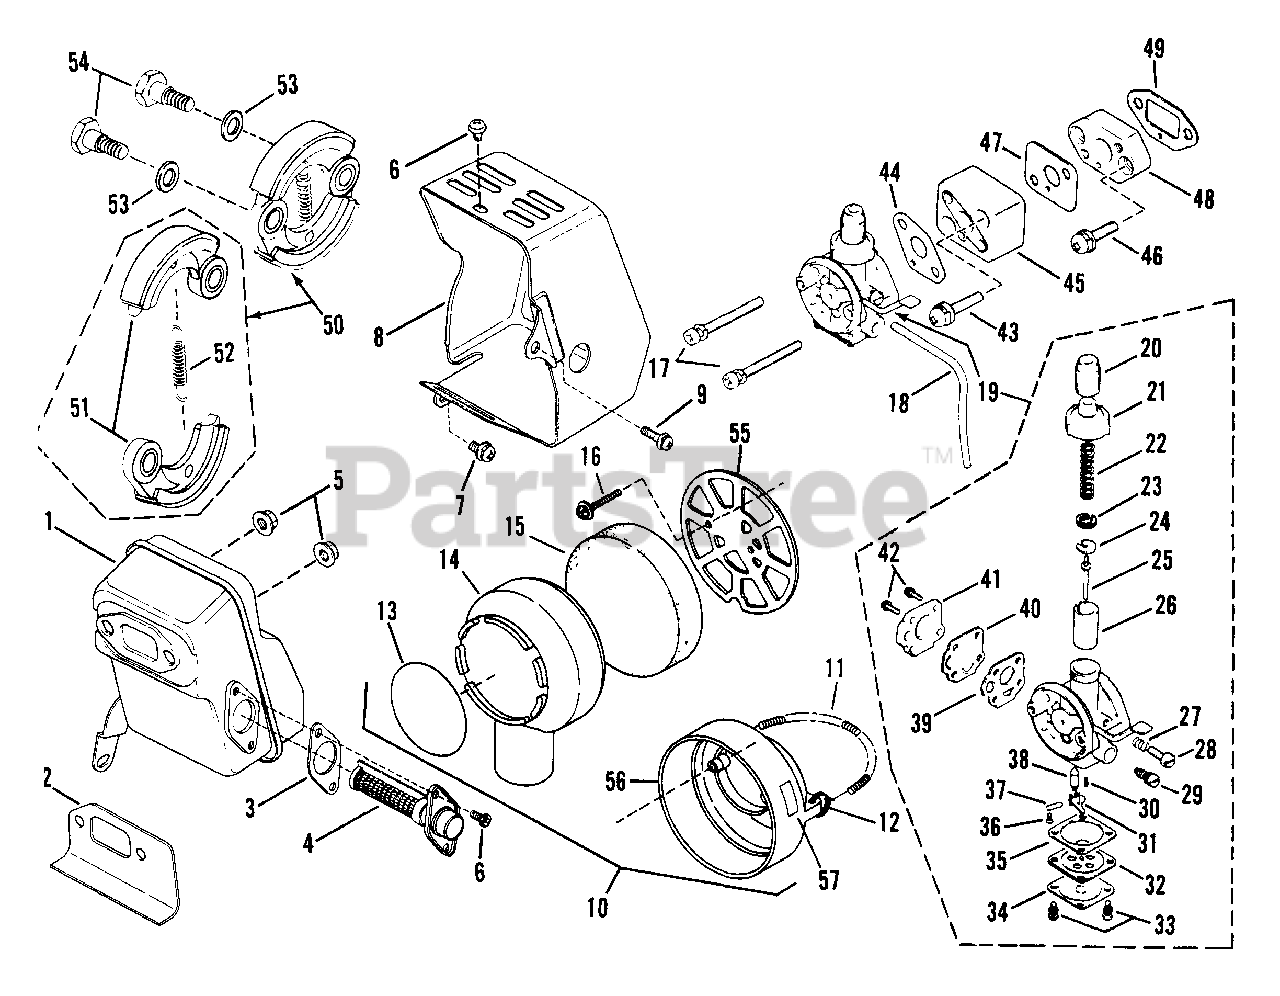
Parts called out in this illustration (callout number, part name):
1	MUFFLER
2	GASKET, Muffler
3	GASKET, Spark Arrester
4	SPARK ARRESTER
5	LOCKNUT
8	COVER, Muffler
9	SCREW
10	ASSM'Y, Air Cleaner
14	COVER, Cleaner
15	ELEMENT
16	SCREW, Cover
17	SCREW, Carburetor
18	TUBE, Overflow
19	CARBURETOR ASSM'Y.
20	CAP, Rubber
21	CAP, Mixing Chamber
22	SPRING, Throttle
23	CLIP, Needle
24	RETAINER, Spring
25	NEEDLE, Jet Assm'y.
26	VALVE, Throttle
27	SPRING, Throttle Adj. Screw
28	SCREW, Throttle Adj.
29	NEEDLE, Main Jet Assm'y.
30	SPRING, Inlet Valve
31	ARM, Float
32	DIAPHRAGM, Main Assm'y.
34	COVER, Main Daiphragm
35	GASKET, Main Diaphragm
36	SCREW, Float Pin Set
37	PIN, Float
38	VALVE, Float
39	GASKET, Main Diaphragm
40	DIAPHRAGM, Pump
44	GASKET, Carburetor
45	FLANGE, Intake (B)
48	FLANGE, Intake (A)
49	GASKET (A)
50	CLUTCH ASSM'Y.
51	SHOE, Clutch
54	BOLT, Clutch
56	CASE, Cleaner
57	LABEL, Choke
